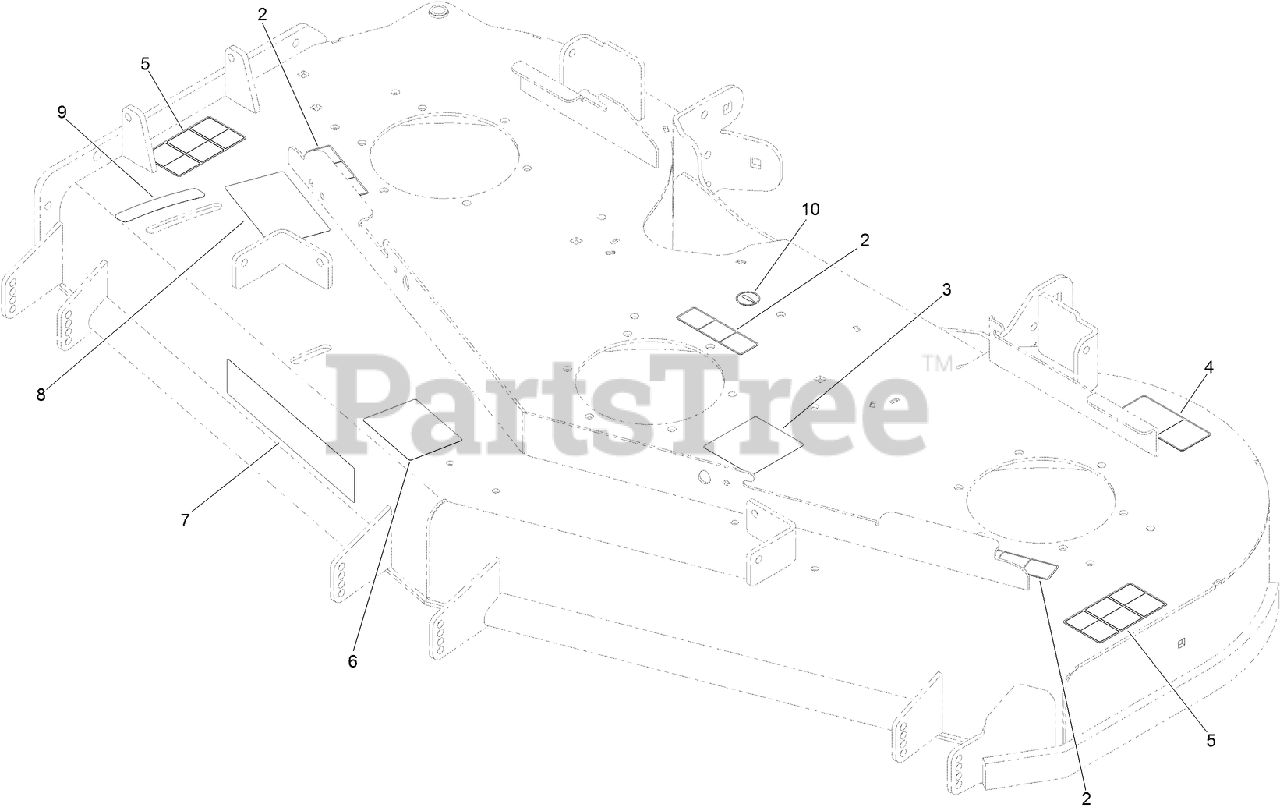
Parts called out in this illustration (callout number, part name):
2	DECAL-COVER, MISSING
3	DECAL-ROUTING, DECK BELT
4	DECAL-TORQUE, BLADE BOLT
5	DECAL-DANGER
6	DECAL-SCALP, ANTI
8	DECAL-ADJUSTMENT, BAFFLE
9	DECAL-SETTING, BAFFLE
10	DECAL-GREASE
